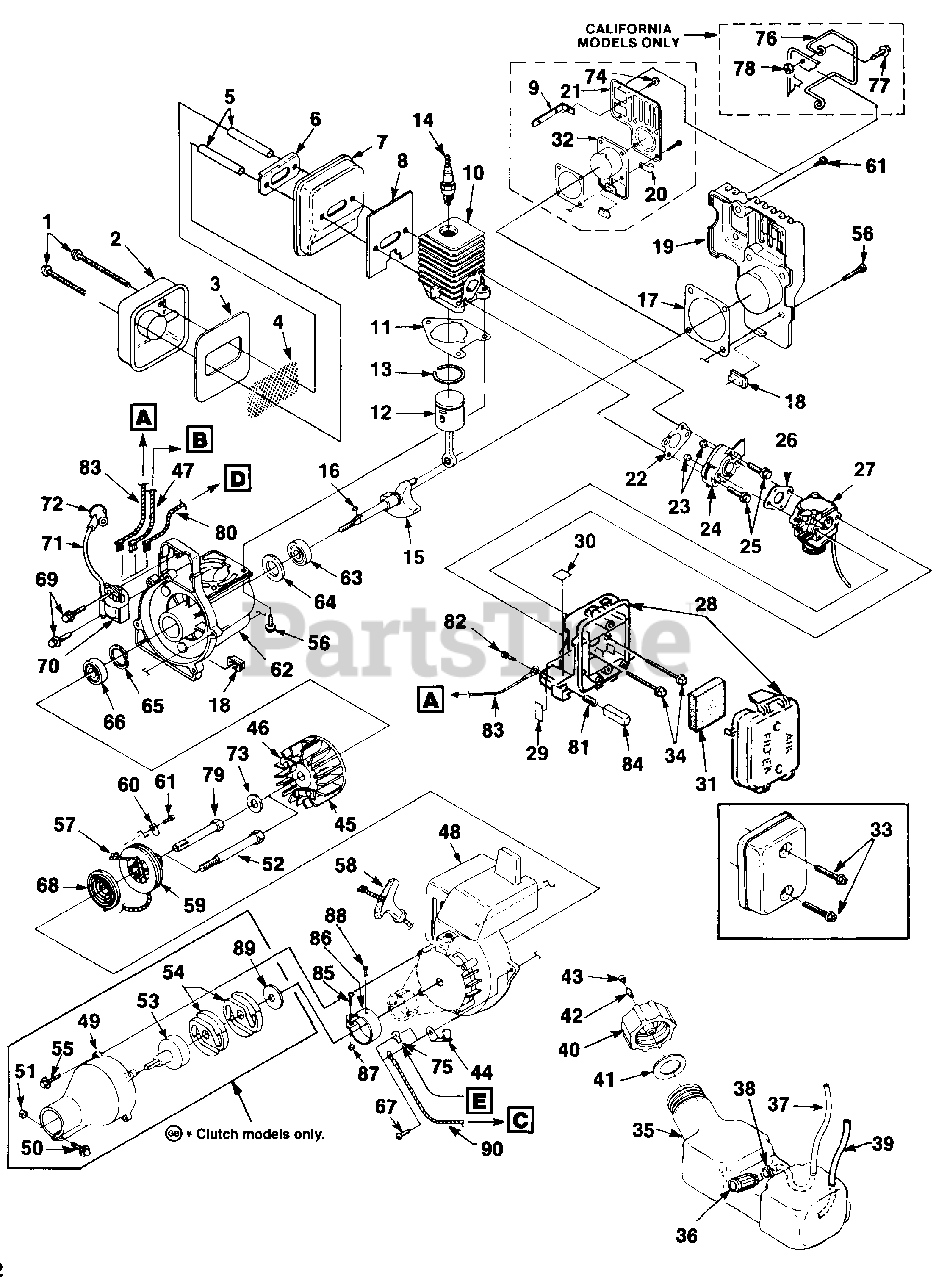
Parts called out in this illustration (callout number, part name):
1	SCREW- (10-24 x 2 1/2")
2	COVER- Muffler
3	BAFFLE- Muffler
4	SCREEN- Spark
5	SPACER- Muffler
6	PLATE- Reinforcing
7	BODY- Muffler
8	GASKET- Muffler
9	BRACKET-
10	CYLINDER
11	CYLINDER- Gasket
12	PISTON & ROD ASSEMBLY
13	RING- Piston
14	SPARK PLUG (DJ7Y)
15	CRANKSHAFT (Model 145 & 155)
16	KEY- Woodruff
17	GASKET- Crankcase cover
18	BUMPER- Rubber
19	COVER- Crankcase
22	GASKET- Heat dam
23	NUT (10-24)
24	HEAT DAM
25	SCREW- Taptite (10-24 x 1")
26	GASKET- Carburetor
27	CARBURETOR- (Zama)
28	AIR FILTER BOX
29	DECAL- Choke, Run
30	DECAL- Push-Hold
31	FILTER- Air
32	COVER- Crankcase
33	SCREW- Plastite (8 x 3/4")
34	SCREW (10-24 x 2 1/4")
35	TANK- Fuel
36	FILTER- Fuel
37	TUBING- Rubber (8")
38	WIRE CLAMP
39	TUBING- Rubber (8")
40	FUEL CAP ASSEMBLY
41	GASKET- Fuel cap
42	VALVE- Duckbill
43	FlLTER-Cap
44	BRACKET-Cable
45	ROTOR
46	KIT- Starter pawl
47	LEAD- Electrical (Models 175BC,185,185C,285BC,385-UT-15040&UT10540-A,
48	HOUSING- Engine (Clutch Models Only)
49	TUBE ADAPTOR
50	SCREW (10-24 x 1 1/4")
51	NUT(10-24)
52	ADAPTOR- Clutch (Clutch Models Only)
53	CONNECTOR & DRUM
55	SCREW (10-24 x 7/8")
56	SCREW (10-24 x 3/4")
57	ROPE- Starter (42")
58	GRIP- Starter
59	PULLEY- Starter
60	BRACKET- Retaining
61	SCREW- Plastite (10 x 1/2")
62	CRANKCASE ASSEMBLY
63	BEARING- Ball
65	RING- Retaining
66	BALL- Bearing
67	SCREW- Taptite (10-24 x 3/4")
68	SPRING & CONTAINER
69	SCREW- Taptite (8-32 x 1")
70	MODULE- Ignition
71	LEAD- High-Tension
72	TERMINAL- High-Tension
73	WASHER- Flat (5/16") (Non-Clutch Models)
74	SCREW- Hex sems (10-24 x 3/8")
75	TERMINAL (Models 385--UT15040B, UT15040C, & UT15040D) (Model 485)
76	WIRE GUARD KIT (California Models Only)
77	SCREW- Hex sems (10-24 x 1/2")
78	NUT- (10-24)
79	CONNECTOR- Drive (Non Clutch Models)
80	LEAD- Electrical (Model 385--UT15040B, UT15040C, UT15040D & Model 485)
81	SPRING- Compression
82	SCREW- Thread Forming
83	LEAD- Electrical (Models 145, 155, 175, 175C, 285, HGT & GST)
84	BUTTON- Switch
85	SCREW- Hex sems (10-24 x 3/8")
86	CLAMP
87	NUT- Square
89	WASHER- Clutch
90	LEAD- Ground (Models 185 & 385--UT15040 & UT15040A)
